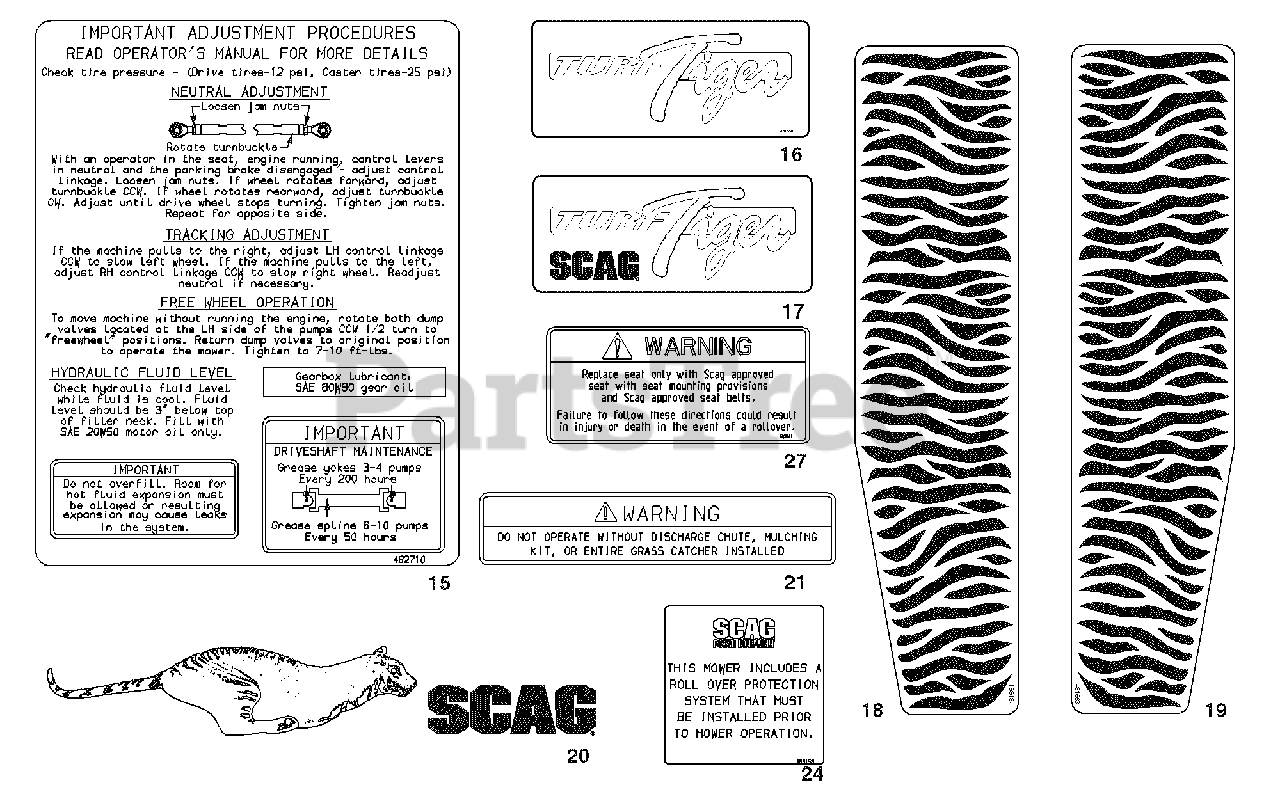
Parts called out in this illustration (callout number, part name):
15	Decal, Seat Support
16	Decal, Turf Tiger
17	Decal, Turf Tiger
18	Decal, Stripes-RH
19	Decal, Stripes-LH
20	Decal, Tiger
21	Decal, Warning
24	Decal, ROPS
27	Decal, Seat Replacement
